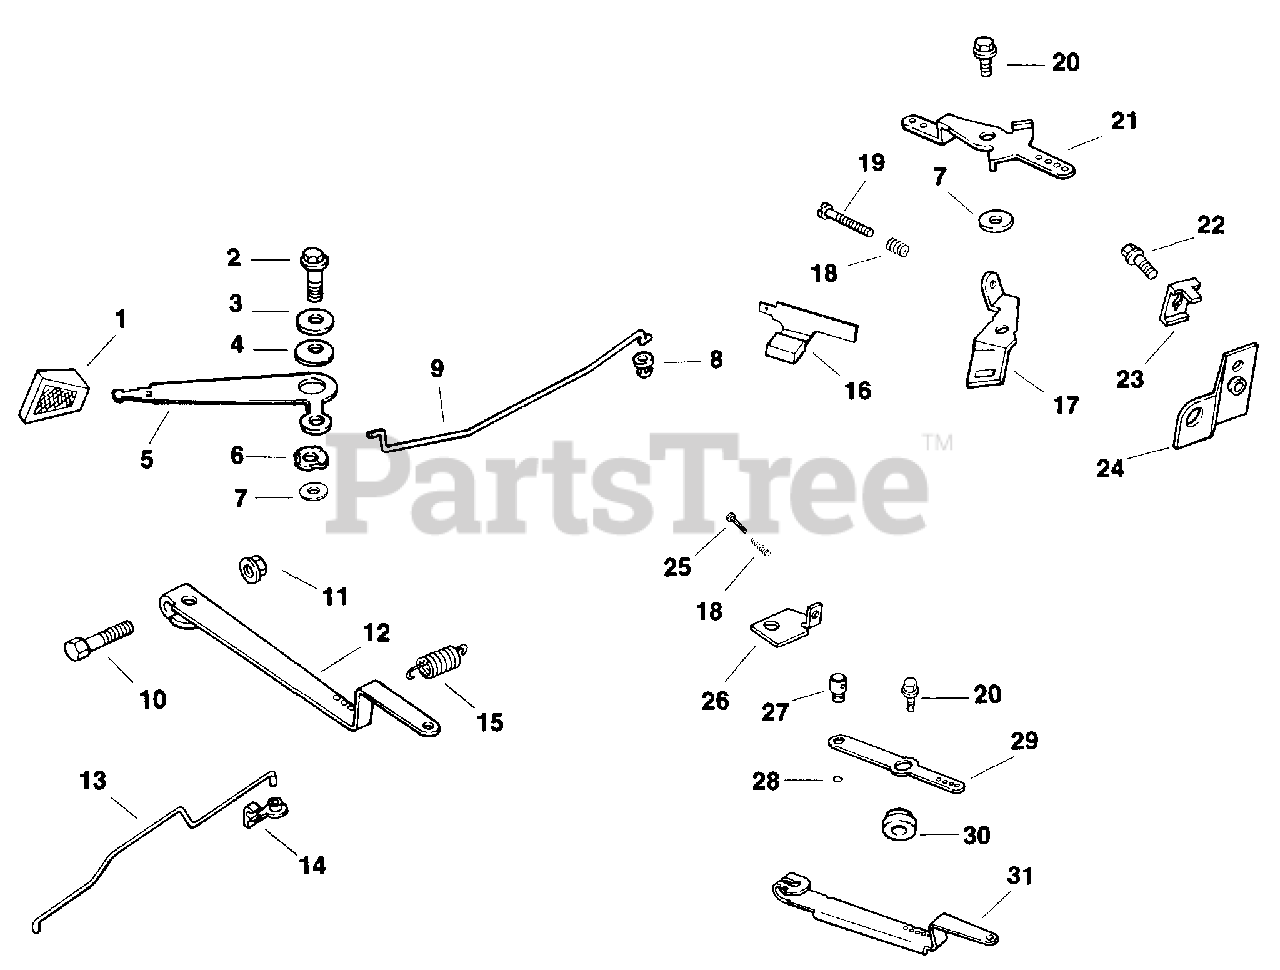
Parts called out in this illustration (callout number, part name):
2	Screw, throttle lever
3	Washer, flat
4	WASHER, SPRING 1/4"
5	LEVER - DISCONTINUED
6	WASHER, SPRING 7/16"
8	BUSHING, LINKAGE RETAINING
9	LINKAGE, SPEED CONTROL
10	USE SM-642025-S
11	Nut, governor output M6x1
14	BUSHING - USE 25 158 11
16	TERMINAL - USE 25 452 13
17	BRACKET - DISCONTINUED
18	SPRING, SPEED CONTROL (SHORT)
19	Screw, sltd. pan hd M4x0.7x25.4
20	Screw, hex flange M6x1.0x20
21	LEVER - DISCONTINUED
22	Screw, cable clamp M5x0.8x16
23	CLAMP, CABLE
24	BRACKET - DISCONTINUED
